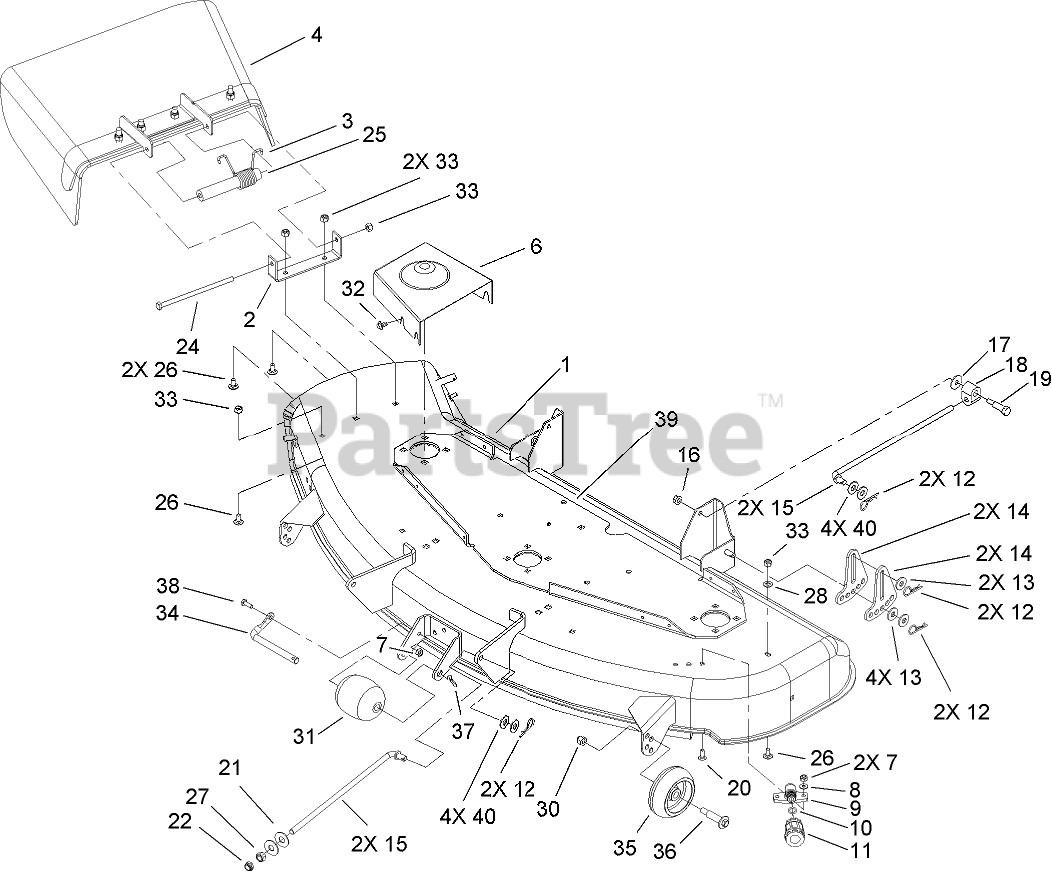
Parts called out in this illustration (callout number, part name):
1	48 INCH DECK ASM
2	BRACKET-PIVOT
3	SPRING-TORSION
4	DEFLECTOR ASM
6	COVER-BELT, RH
7	NUT-LOCK, NI
8	WASHER-FLAT
9	FITTING-WASHOUT
10	O-RING
11	CONNECTOR-HOSE
12	PIN-HAIR
13	WASHER-HARDENED
14	LINK-ADJUSTING, HOC
15	ROD-HANGER
16	NUT-HF
17	WASHER-PIVOT
18	TRUNNION-HOC
19	SCREW-SHOULDER, HH
20	BOLT-CARR
21	WASHER-FLAT
22	NUT-LOCK, NI
24	BOLT-HH
25	SPACER-DEFLECTOR
26	SCREW-CARR
27	NUT-HEX
28	WASHER-PLAIN
30	NUT-LOCK, NI
31	ROLLER
32	SCREW-HHFTF
33	NUT-LOCK, NI
34	ROLLER-SHAFT
35	WHEEL-GAGE
36	SCREW-SHOULDER, HWH
37	PIN-COTTER
38	SCREW-HH
39	PLATE-REINFORCEMENT, DECK
40	WASHER-FLAT
